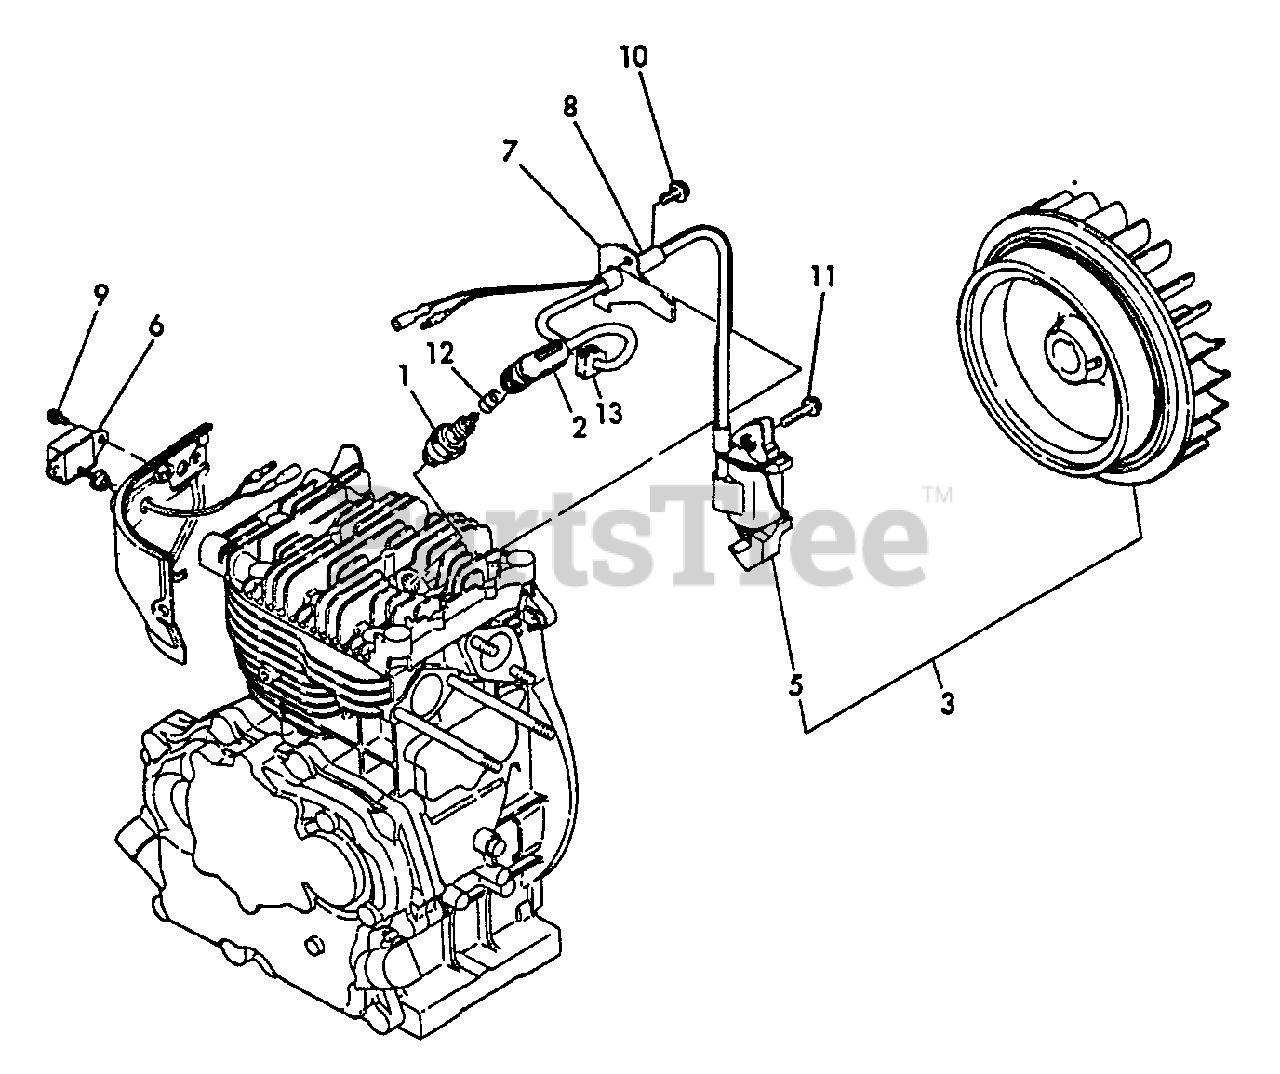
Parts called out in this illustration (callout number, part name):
1	SPARK PLUG
2	CAP, PLUG
3	FLYWHEEL W/MAGNET
5	COIL, IGNITION
6	IGNITER
7	CLAMP
8	TUBE, INSULATOR
9	SCREW - 5X10
10	BOLT - 6X8 -- PLATED
11	BOLT - 6X25
12	TERMINAL, SPARK PLUG CAP
13	GROMMET
